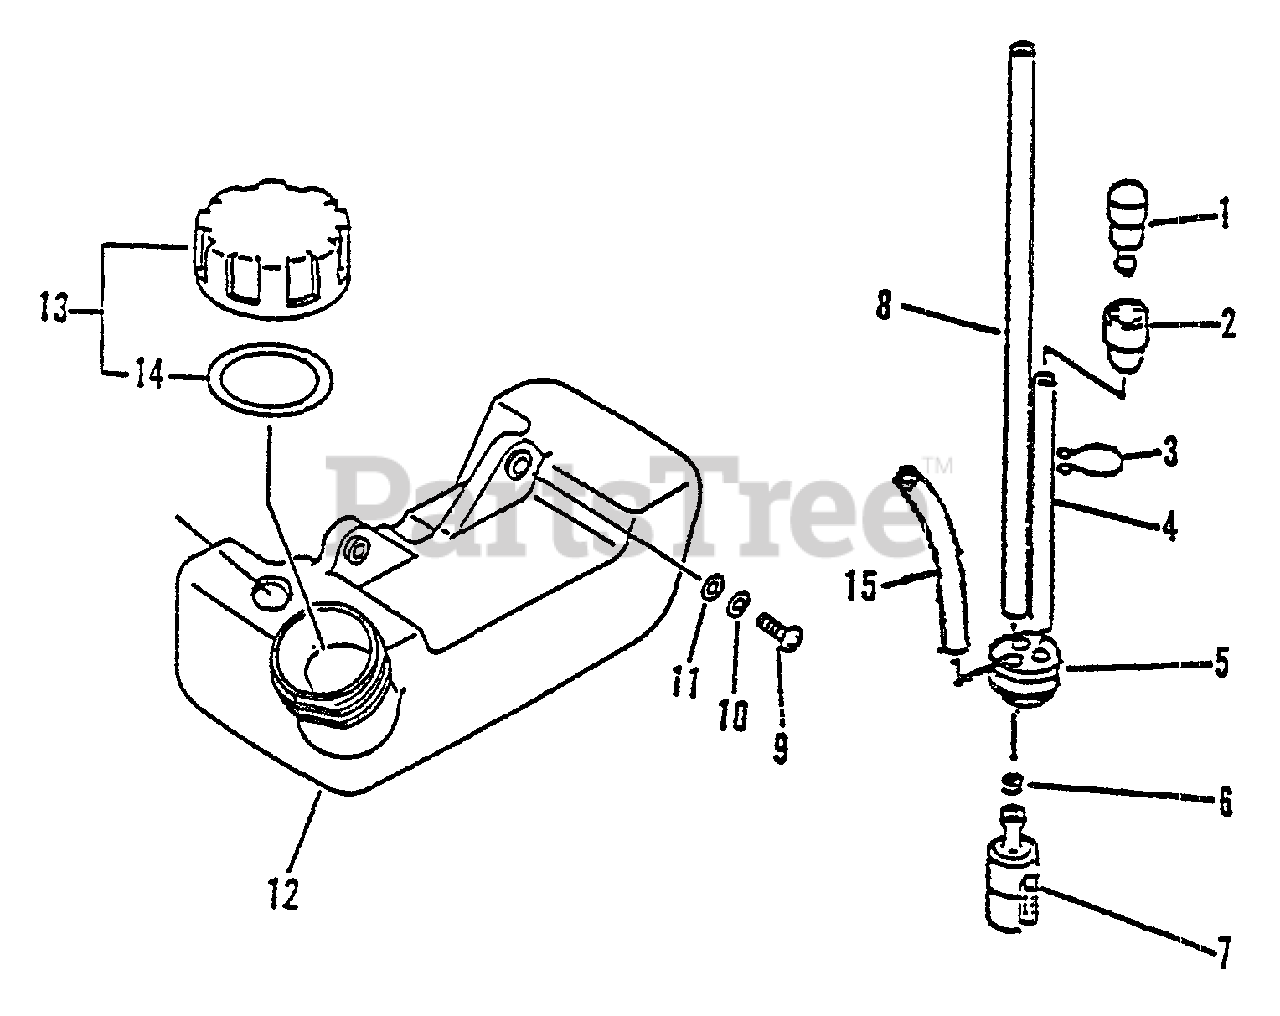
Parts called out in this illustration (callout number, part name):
1	VENT ASSY
2	HOLDER, VENT
3	CLIP, TUBE
4	PIPE, FUEL 3x-5x-70 BLACK
5	GROMMET, FUEL
6	CLIP 6 MM
7	FILTER, FUEL
8	PIPE, FUEL 3x-5x-180
9	SCREW 5×16
10	WASHER, SPRING 5
11	WASHER 5.5×12×0.8
12	TANK, FUEL
13	CAP ASSY
14	GASKET, FUEL CAP
15	PIPE, FUEL RETURN 3×6×90 MM CLEAR
